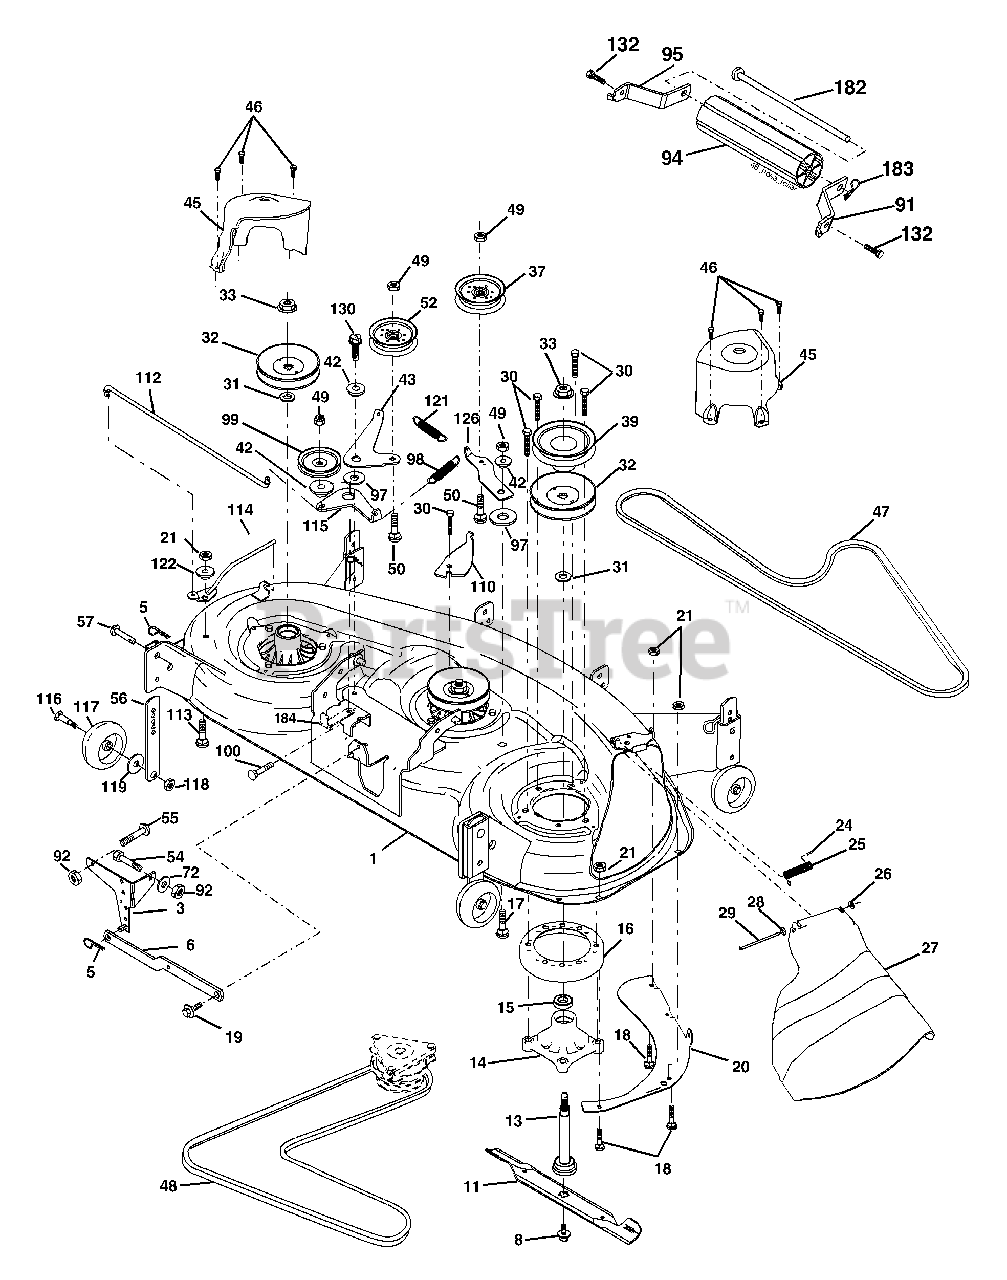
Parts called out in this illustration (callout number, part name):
1	Deck Weldment Mower 48
3	Bracket Asm., Sway Bar
5	Retainer Spring
6	Arm, Suspension, Rear Sway Bar Deck
8	Bolt 7/16 Asm. Blade
11	Blade, 48" Mulching
11	Blade, 48" Hi-Lift
13	Shaft Asm. w/Lower Bearing
14	Mandrel Asm. Housing
15	Bearing, Ball, Mandrel
16	Stripper Mandrel Deck
17	Bolt RDHD Sq Neck 3/8-16 x 1.25
18	Bolt, Carriage 5/16-18 x 5/8
19	Bolt, Hex Hd, Shoulder 5/16-18
20	Baffle, Vortex Mower
21	Nut, Crownlock 5/16-18 unc
24	Cap, Sleeve
25	Spring, Torsion
26	Nut, Push
27	Deflector Shield
28	Washer 11/32 x 5/8 x 16 Ga.
29	Rod, Hinge
30	Screw, Thdroll Washer Head
31	Washer, Spacer
32	Pulley, Mandrel
33	Nut, Flg. Top Lock Cntr. 9/16
36	Washer 13/32 x 13/16 x 16 Ga.
37	Pulley, Idler, Flat
39	Pulley, Idler, Driven
42	Spacer, Retainer
43	Arm, Idler Secondary
45	Cover, Mandrel Deck
46	Screw, Thdroll. 1/4-20 x 5/8
47	V-Belt, Mower, Secondary
48	V-Belt, Mower, Primary
49	Nut, Lock 3/8-16 unc
50	Bolt, Carr. 3/8-16 x 1-1/2 Gr. 5
52	Pulley Idler Flat
54	Bolt Fin Hex 3/8-16 x 1
55	Bolt Carriage Sqnk. 3/8-16 x 1
56	Bar Pnt Adj.
57	Pin Head Rivet
72	Washer 13/32 x 13/16 x 12 Ga.
91	Bracket, Asm Noseroller, RH
92	Nut Lock Hex 3/8-16
94	Noseroller
95	Bracket, Asm Noseroller LH
97	Washer Hardened
98	Spring Primary Drive
99	Pulley Idler "V"
100	Bolt RDHD Sqnk 3/8-16 unc x 2
110	Arm Spring Secondary
112	Link Tension Relief Lever
113	Bolt 5/16-18 x 3/4
114	Tension Asm. Relief Lever
115	Arm Spring Tension Relief
116	Bolt, Shoulder
117	Gauge Wheel
118	Nut, Centerlock 3/8-16 unc
119	Washer 3/8 x 7/8 x 14 Ga.
121	Spring Secondary Drive
122	Bushing Pivot Tension Relief
126	Arm, Idler, Primary Deck
130	Screw 3/8-16 x 1.0
132	Screw 3/8-16 x .75
182	Rod Roller Nose
183	Retainer Spring
184	Keeper Belt Idler
